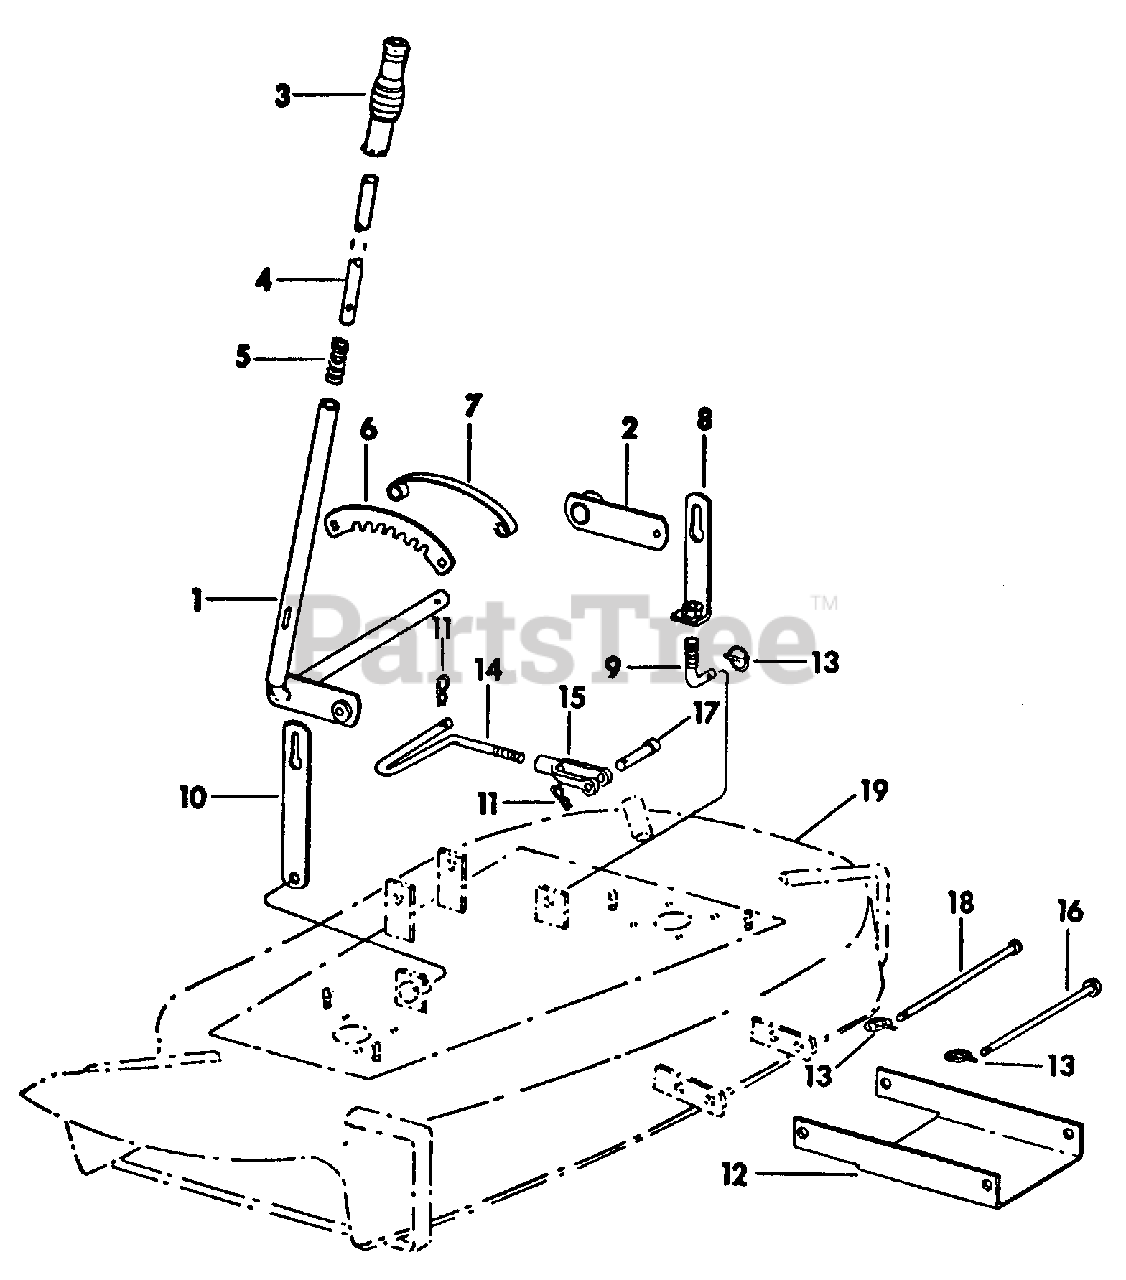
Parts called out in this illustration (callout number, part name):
1	Handle Assy, Lift
2	Arm Assy, Lift Handle LH
3	Grip, Lift Handle
4	Button, Lift Handle
5	Spring, Lift Button
6	Ratchet, Lift
7	Spacer, Ratchet
8	Support Assy, Lift (Link)
9	Rod, Lift Link
14	Rod, Mower Linkage
15	Clevis, Short Adj Rod End
16	Pin, 1/2 X 7.688 Std Hd
17	Pin, 1/2 X 2-3/32 Rod End
18	Pin, 1/2 X 7 Znd Std Hd
19	Housing Assy, Mower
